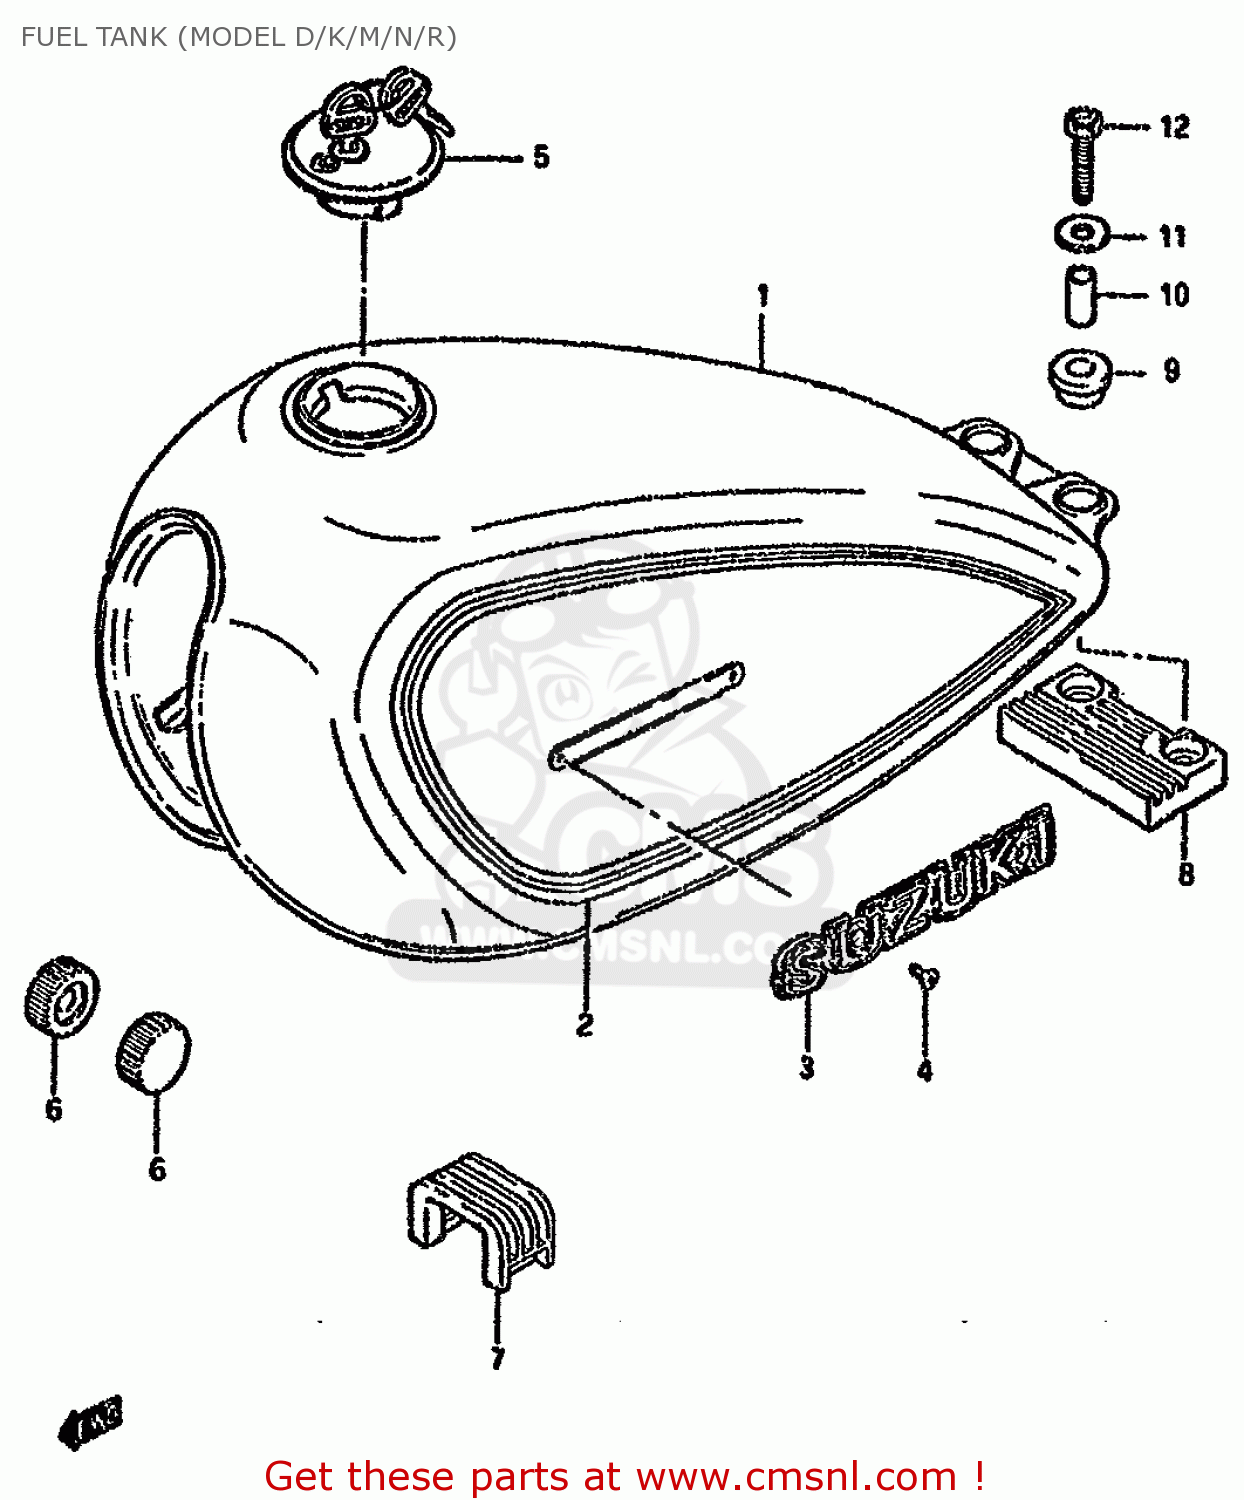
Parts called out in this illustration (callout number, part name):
1	TANK ASSEMBLY,FUEL
2	TAPE SET,FUEL TANK
3	EMBLEM,FUEL TANK
4	SCREW
5	CAP SET,FUEL TANK
6	CUSHION
7	CUSHION,FUEL TANK UPR FR
8	CUSHION,TANK RR NO.1
9	CUSHION
10	SPACER(6.5X10.5X22.5)
11	WASHER(6,5X22X1.6)
12	BOLT(6X35)
